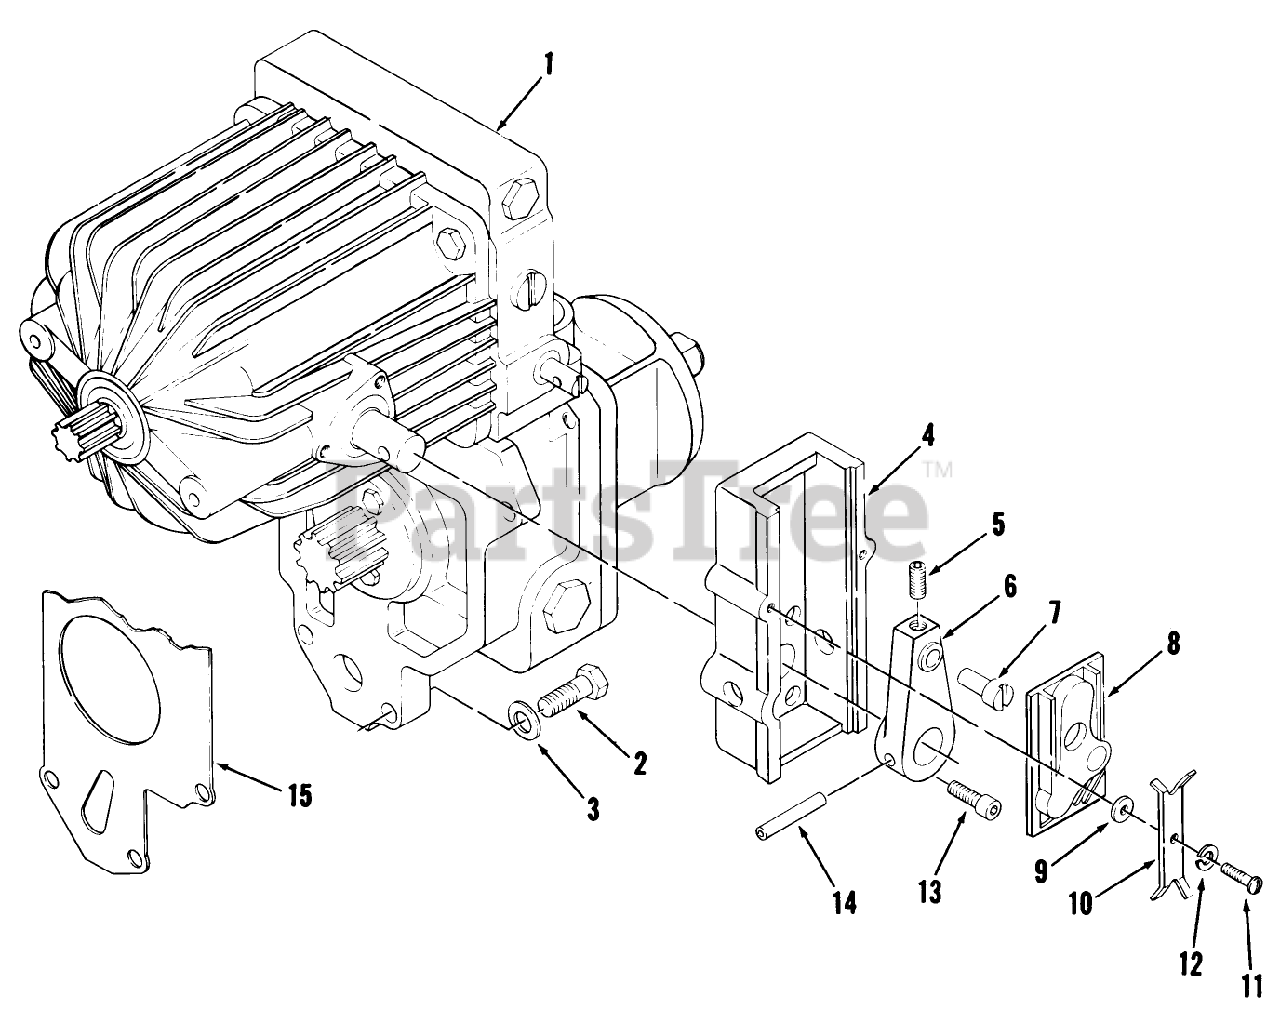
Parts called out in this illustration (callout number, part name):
1	SER BULLT 437B
8	CAM
15	GASKET
